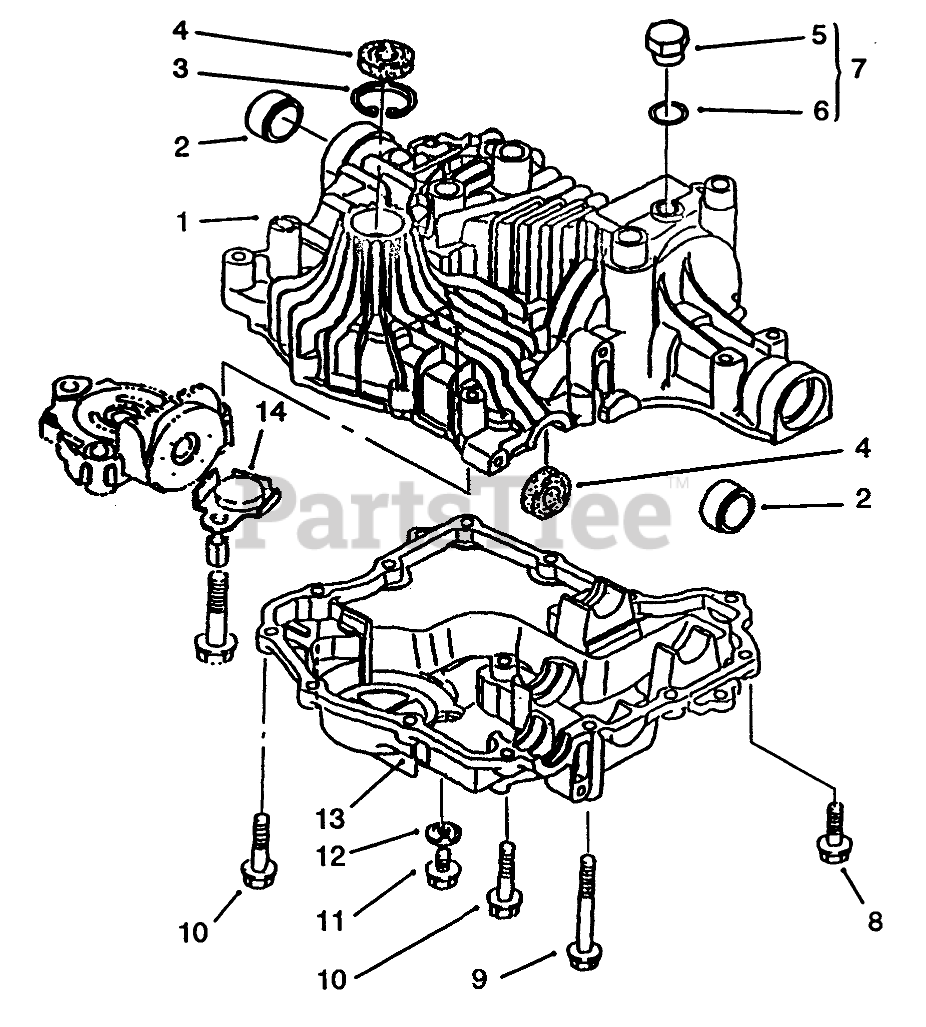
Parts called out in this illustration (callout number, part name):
1	Upper Case ASM INC 2-6 (Only On: 72083, 72043, 72103, 72063)
3	Ring (Only On: 72083, 72043, 72103, 72063)
4	Seal (Only On: 72083, 72043, 72103, 72063)
7	Plug/Packing INC 5-6 (Only On: 72083, 72043, 72103, 72063)
8	Screw-TAP (Only On: 72083, 72043, 72103, 72063)
9	Bolt (Only On: 72083, 72043, 72103, 72063)
10	Screw-TAP (Only On: 72083, 72043, 72103, 72063)
11	Bolt (Only On: 72083, 72043, 72103, 72063)
13	Case-Lower (Only On: 72083, 72043, 72103, 72063)
14	Magnet (Only On: 72083, 72043, 72103, 72063)
